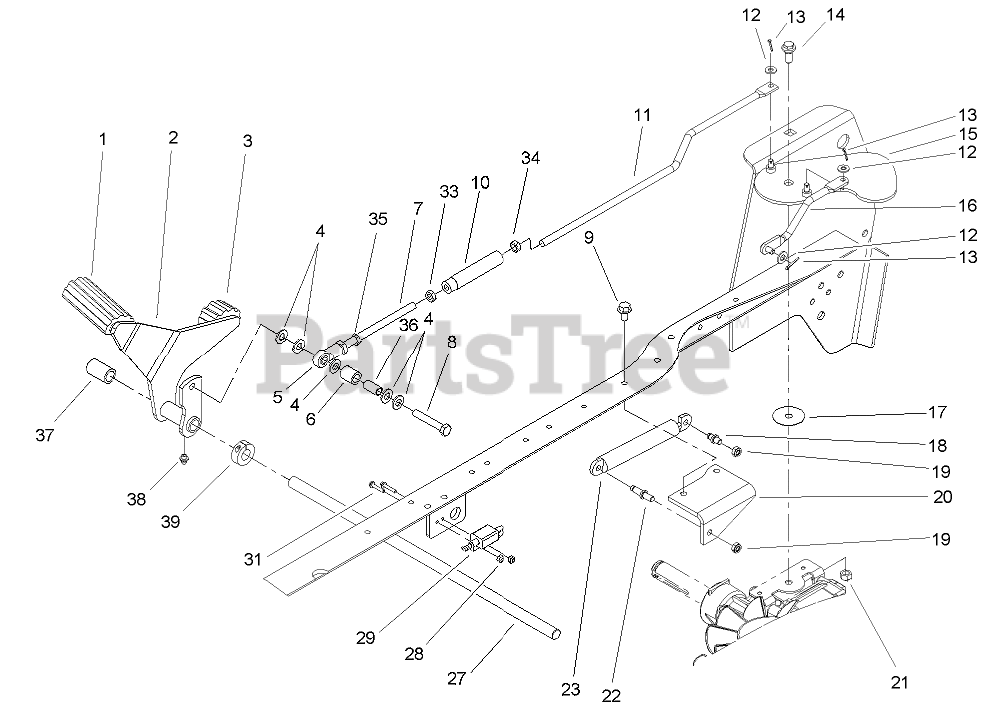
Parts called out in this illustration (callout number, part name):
1	PAD-PEDAL
2	HYDRO PEDAL ASM
3	PAD-PEDAL
4	WASHER-FLAT
5	END-ROD, FEMALE
6	SPACER-INTERLOCK
7	ROD-HYDRO, FRONT
8	SCREW-HH
9	SCREW-HWHTF
10	TURNBUCKLE
11	ROD-HYDRO, REAR
12	WASHER-PLAIN
13	PIN-COTTER
14	BOLT-SHOULDER
15	CRUISE PLATE ASM
16	BELL CRANK ROD ASM
17	SPACER-CRUISE
18	ARM-CONTROL, PIN DAMPER
19	NUT-LOCK, NI
20	BRACKET-DAMPER
22	PIN-BRACKET, DAMPER
23	DAMPER-GAS
27	SHAFT-PIVOT, PEDAL
28	NUT-LOCK
29	SWITCH-ADJUSTABLE
31	SCREW-SHWH
33	NUT-HJ
34	NUT-JAM
35	NUT-JAM
36	SLEEVE-BEARING
37	SPACER
38	FITTING-GREASE
39	COLLAR-LOCKING
